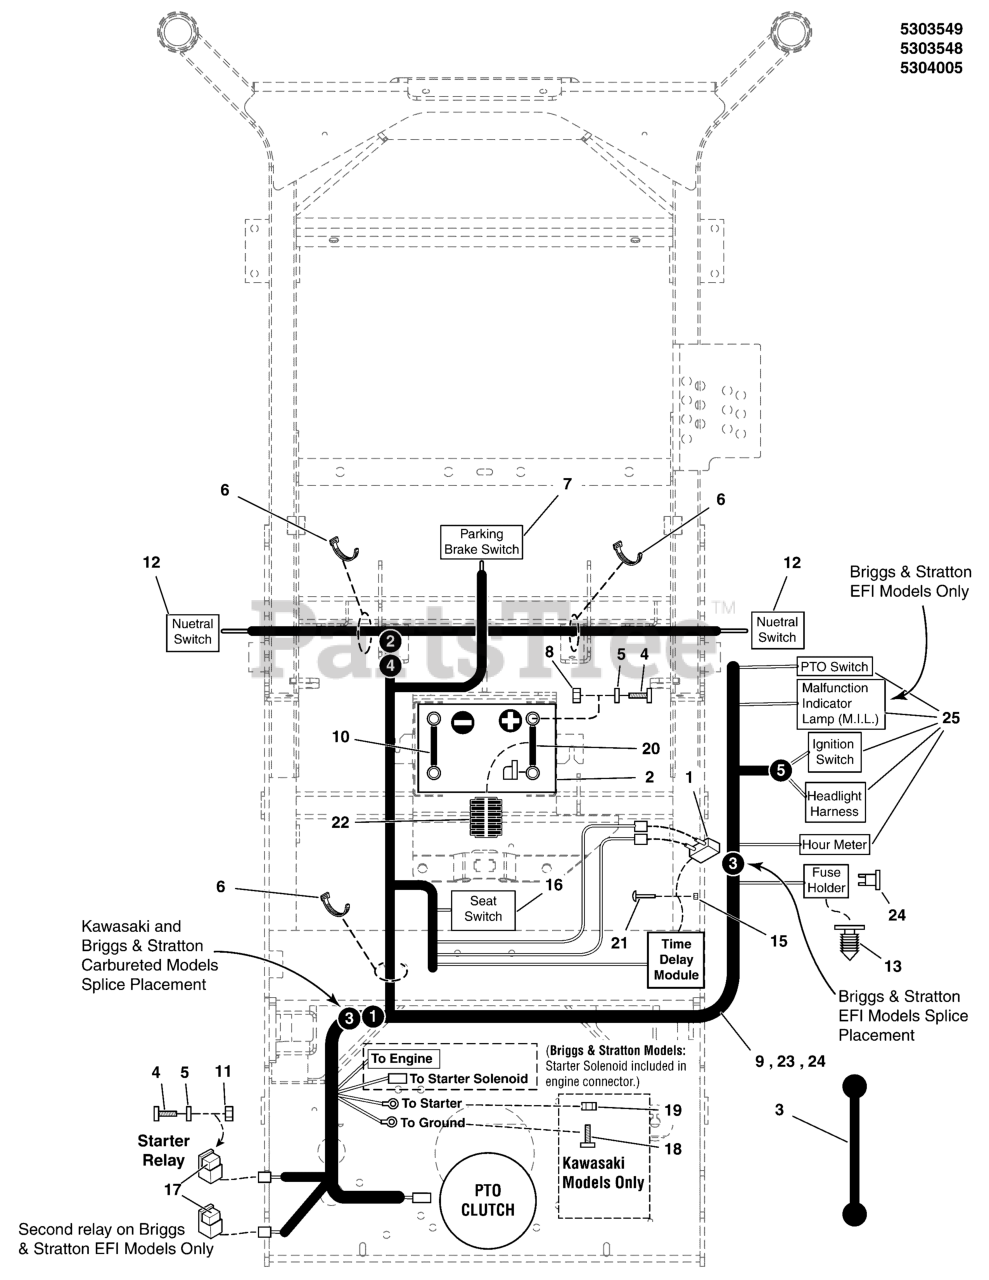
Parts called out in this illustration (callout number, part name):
1	BREAKER-CIRCUIT 12VOLT 20AMPS W/TAB
2	BATTERY, 11U1L, 350 CCA
3	STRAP-BLACK RUBB
4	BOLT, 1/4-20 X 3/4 GD5 YZ
5	WASHER, 1/4 SAE
6	TIE, SELF-LOCKING, 12"
7	SWITCH, DP NO/NC SNAP-IN
8	NUT, 1/4-20 HEX SERR. FLANGE
9	WIRE HARNESS, S150XT, KAWI FX
10	BATTERY CABLE, NEG, 30, 1/4-5/16
11	NUT, 1/4-20 HEX NYLOCK FLANGE
12	SWITCH, LOW PROF, NC/NO
13	FIR TREE MOUNT, PACKARD
14	MODULE, TIME DELAY
15	NUT, #10-24 HEX NYLON LOCK
16	SWITCH, PLUNGER, NO, SINGLE POLE SNAP-IN
17	RELAY, 12V, 40A
18	BOLT, M8-1.25 X 20MM GD8.8
19	NUT, HEX, M8-1.25, CZ, GD 8.8
20	BATTERY CABLE, POS, 35, 1/4-5/16
21	SCREW, #10-24 X 3/4 ROUND PHILLIPS
22	WIRE LOOM, 3/8 ID X 30 IN
23	WIRE HARNESS, S150XT, B&S-VANG
24	WIRE HARNESS, S150XT, B&S-VANG EFI
